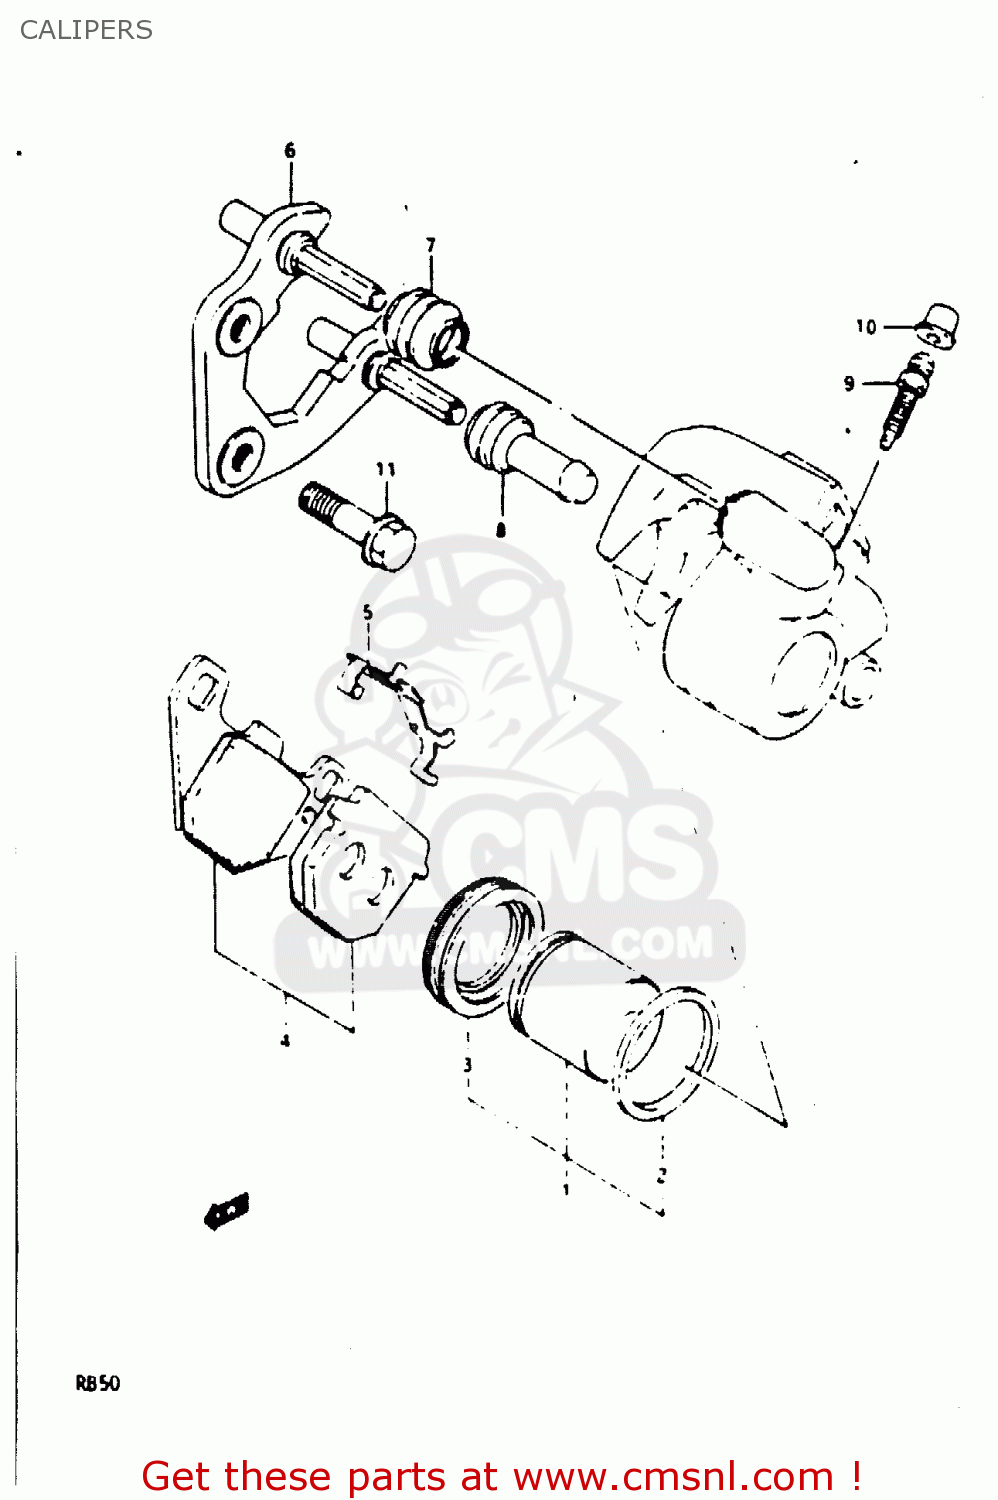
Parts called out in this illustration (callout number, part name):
1	PISTON SET
2	SEAL
3	BOOT
4	PAD SET (NAS)
5	SPRING,PAD
6	CARRIER,L
7	BOOT,AXLE
8	INSULATOR,AXLE
9	BLEEDER
10	CAP,BREATHER
11	BOLT 8X30
